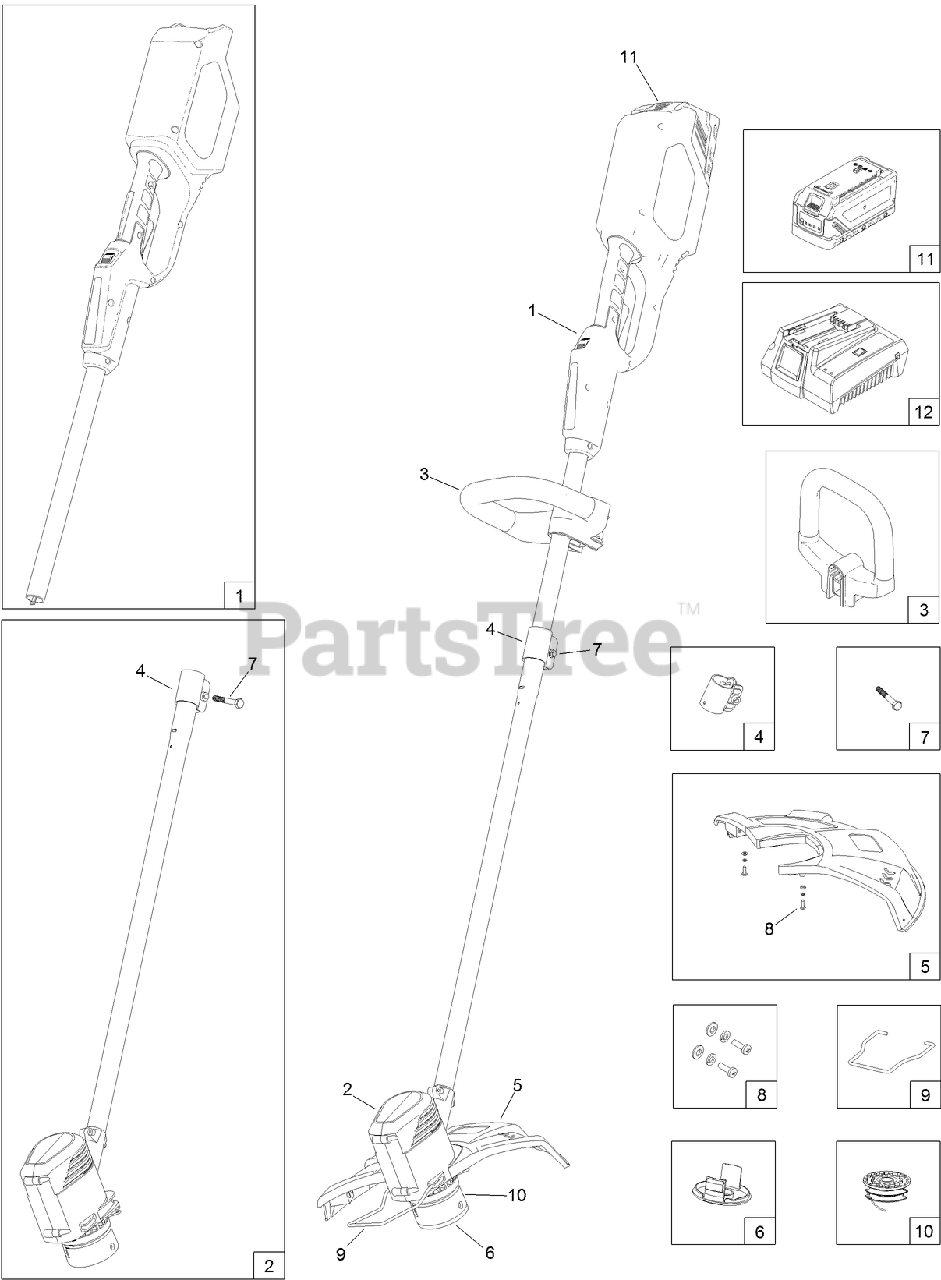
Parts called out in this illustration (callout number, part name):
1	UPPER HANDLE ASM
2	HOUSING-MOTOR, LOWER
3	HANDLE-ASSIST
4	CLAMP-CONNECTION, SHAFT
5	GRASS SHIELD ASM
6	CAP-RETAINER, SPOOL
8	SCREW WITH WASHERS ASM
9	WIRE-GUIDE, STRING TRIMMER
10	TRIMMER SPOOL-DUAL LINE, 1-PACK
11	BATTERY-48V (2AH)
12	CHARGER-48V
